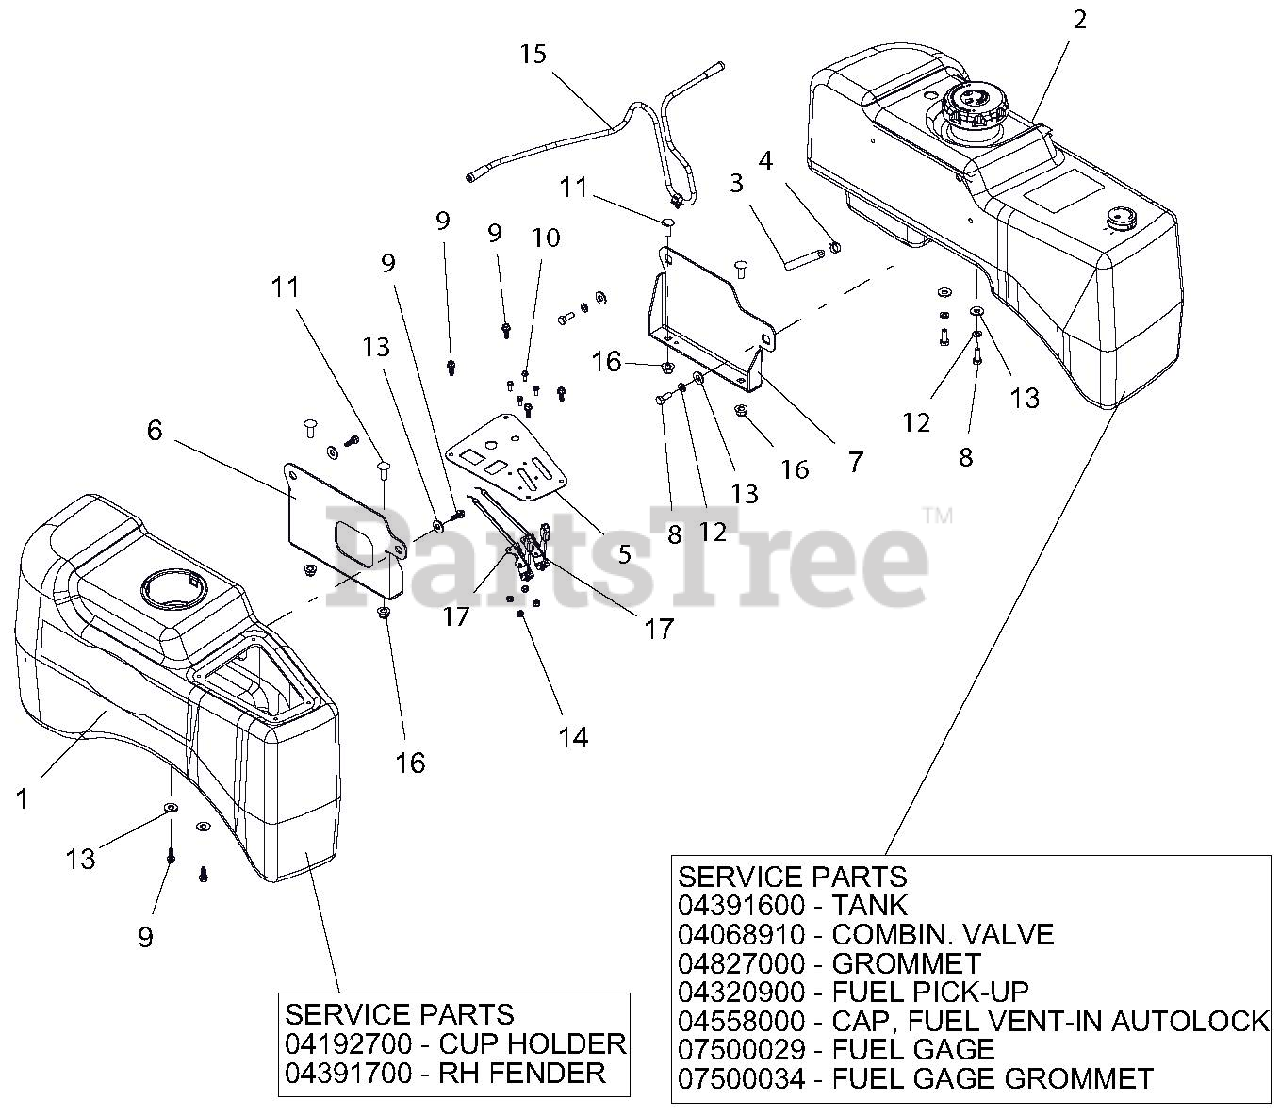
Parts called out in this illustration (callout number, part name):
1	ASM, FENDER W/CUPHOLDER
1	CUP HOLDER
1	RH FENDER
2	HD, FUEL TANK ASSEMBLY
2	TANK
2	COMBIN. VALVE
2	GROMMET
2	FUEL PICK-UP
2	CAP, FUEL VENT-IN AUTOLOCK
2	FUEL GAUGE
2	FUEL GAUGE GROMMET
3	.25 LOW-PERM GAS HOSE 18.50" LG - TANK TO ENGINE
4	CLAMP, FUEL LINE
5	PANEL, INSTRUMENT-BLACK
6	BRKT, RH HD FUEL TANK MTG-RED
7	BRKT, LH HD FUEL TANK MTG-RED
8	BLT-HEX .31-18X.875 GR5 YWZC
9	SCR-PLASTITE .25-10X.75 YWZC
10	@SCR-MCH 10-24X.50 HWH YWZC
11	BLT-RDHDSHSQNK.38-16X1.0 G5YZ
12	WSHR-LK .31X.078 REG YWZC
13	WSHR-FL-STL.38X.875X.083 YWZC
14	NUT-LK-NYL #10-24 YWZC
15	KAWASAKI, VENT LINE HD/PRO-TURN
16	NUT-LK-NYL-FLG .38-16 YWZC
17	CABLE, CONTROL
